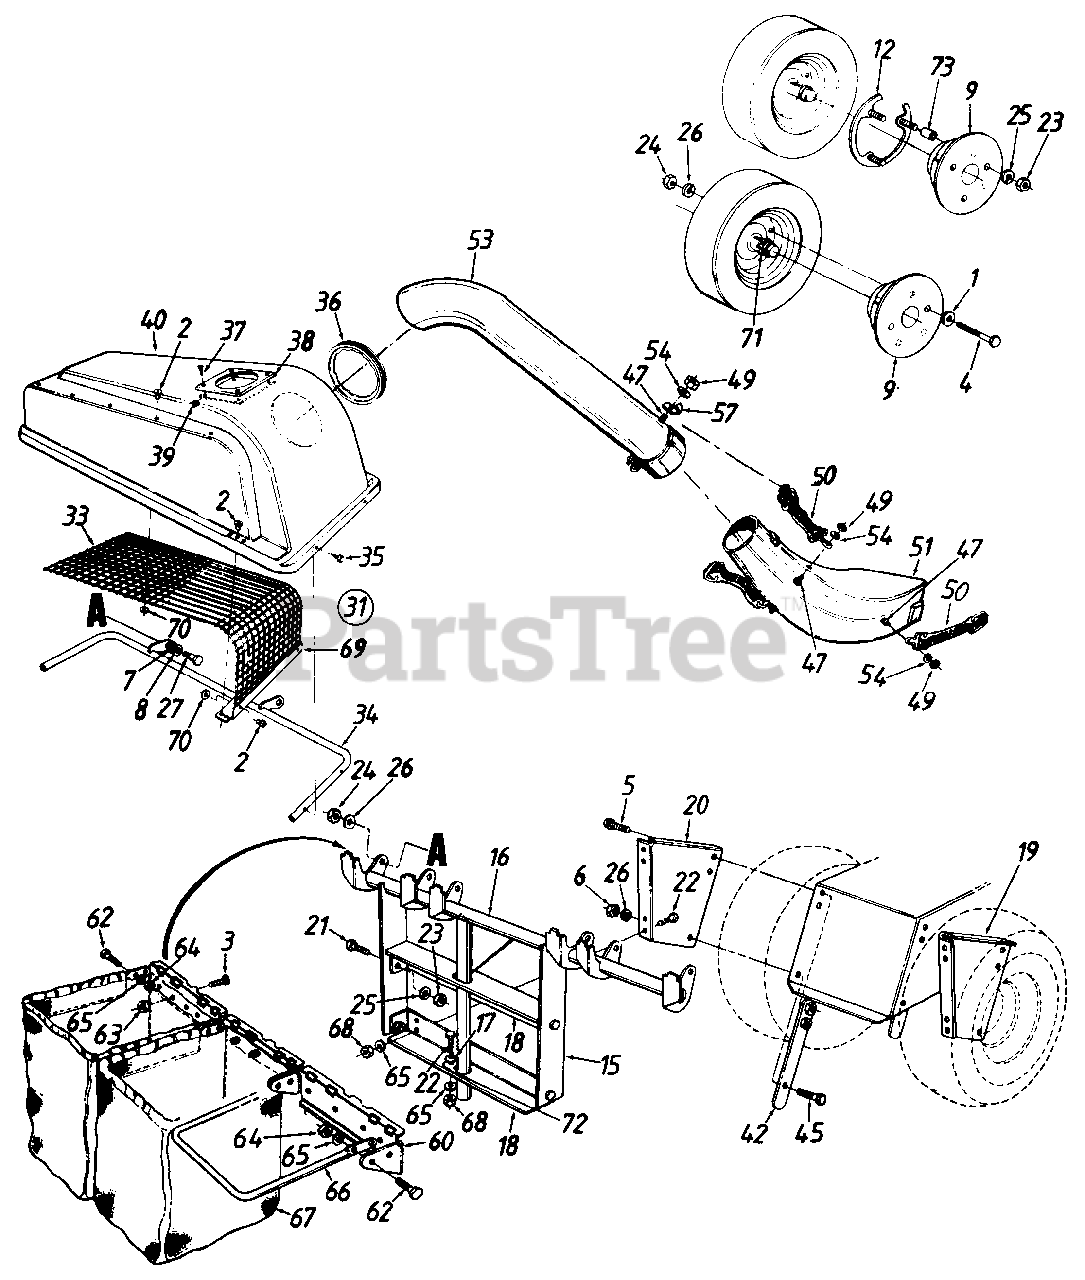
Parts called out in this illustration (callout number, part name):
1	Fl-Wash. .385" I.D.
2	pop Rivet
3	Truss Mach. Scr. #10-24 x .38" Lg.
4	Hex Bolt 3/8-16 x 4.5" Lg.
5	Hex Wash. Hd. Tap Scr. 5/16-18 x .62"
6	Hex Nut 3/8-24 Thd.
7	Bell-Wash. .515" l.D.
8	Fl-Wash. .510" I.D.
9	Wheel Weight
12	Wheel Weight Snap Ring
15	Catcher Support Tube Mtg. Brkt.
18	Catcher Latch and Support Brkt.
22	Hex Bolt 1/4-20 x .62" Lg.-Grade 5
23	Hex Nut 5/16-18 Thd.
24	Hex Nut 3/8-16 Thd.
25	L-Wash. 5/16" l.D.
26	L-Wash. 3/8" l.D.
27	Shld. Bolt 3/8-16 x .500" Dia.
31	Grass Catcher Cover Ass'y. Comp.
37	Truss Mach. B-Tap Scr. #10 x 5" Lg
38	Plastic Plate
39	Speed Nut
40	Grass Catcher Cover
47	Hex Bolt 1/4-20 x 50" Lg.
49	Hex Ins. L-Nut 1/4-20 Thd.
50	Retainer Strap Ass'y.
51	Discharge Chute
53	Catcher Elbow Tube
54	L-Wash. .270" l.D. x 57" O.D.
57	Retainer Hook Brkt.
62	Hex Bolt 1/4-28 x 75" Lg.
63	Hex Sems Nut #10-24 Thd.
64	Hex Nut 1/4-28 Thd.
65	L-Wash. 1/4" l.D.
66	Catcher Bag Frame
67	Grass Catcher Bag
68	Hex Nut 1/4-20 Thd.
71	Foam Strip 1-1/8" x 1-1/2 x 3/8
